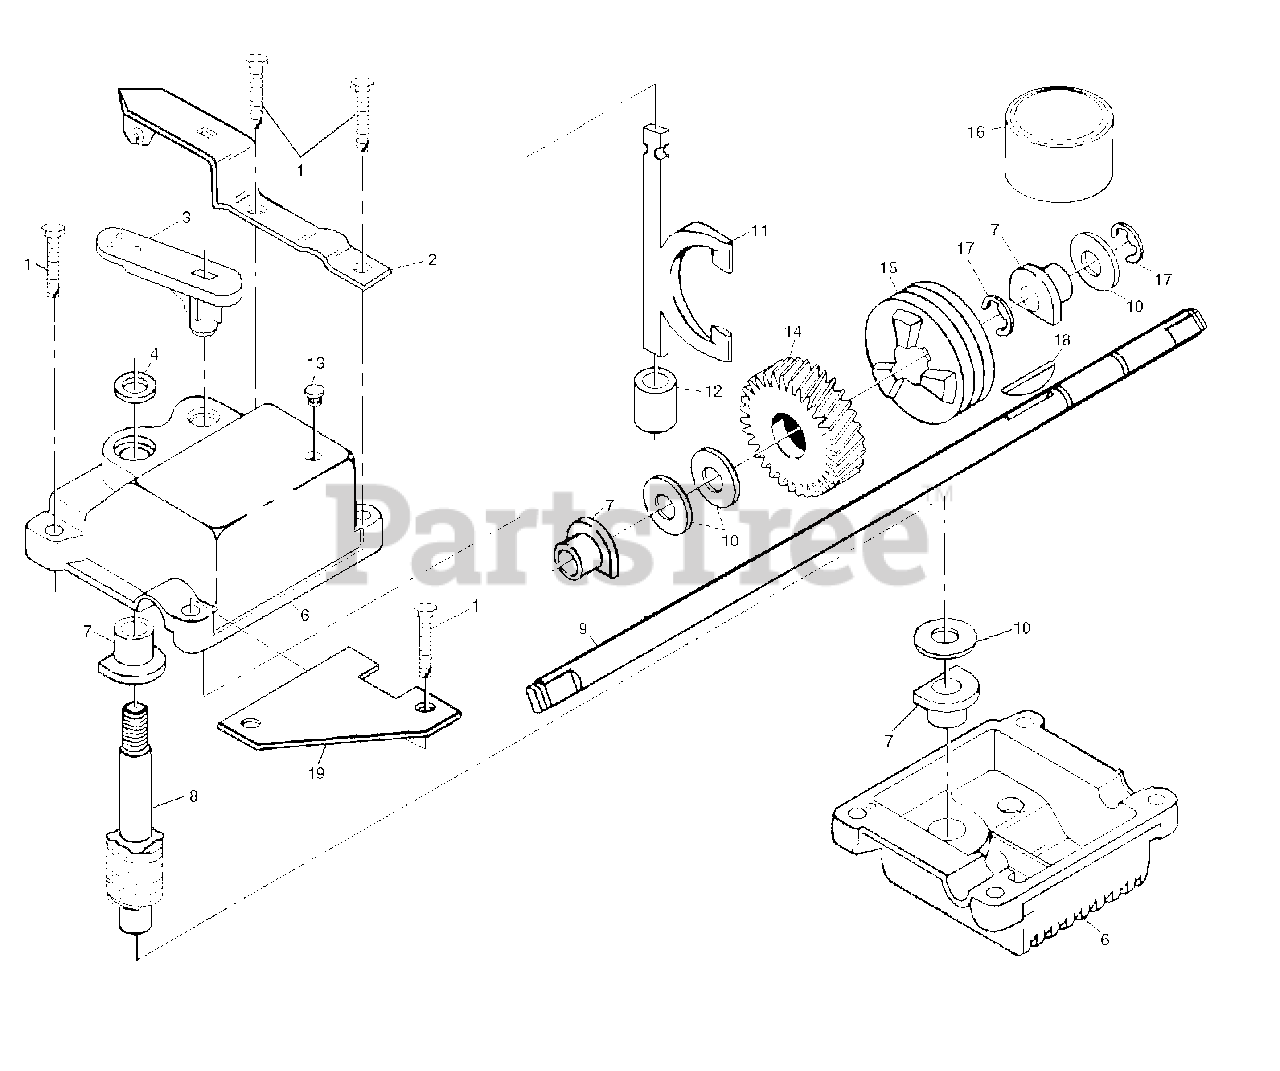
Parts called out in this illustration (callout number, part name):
1	Tapping Screw 1/4-20 x 1-1/4
2	Engagement Bracket
3	Shifter
4	Seal
6	Gear Case Halves Kit
7	Bearing
8	Worm Shaft
9	Drive Shaft
10	Hardened Washer
11	Clutch Yoke
12	Bushing
13	Plug
14	Helical Gear
15	Clutch Jaw
17	E-Ring
18	Hi-Pro Key
19	Spring Bracket
